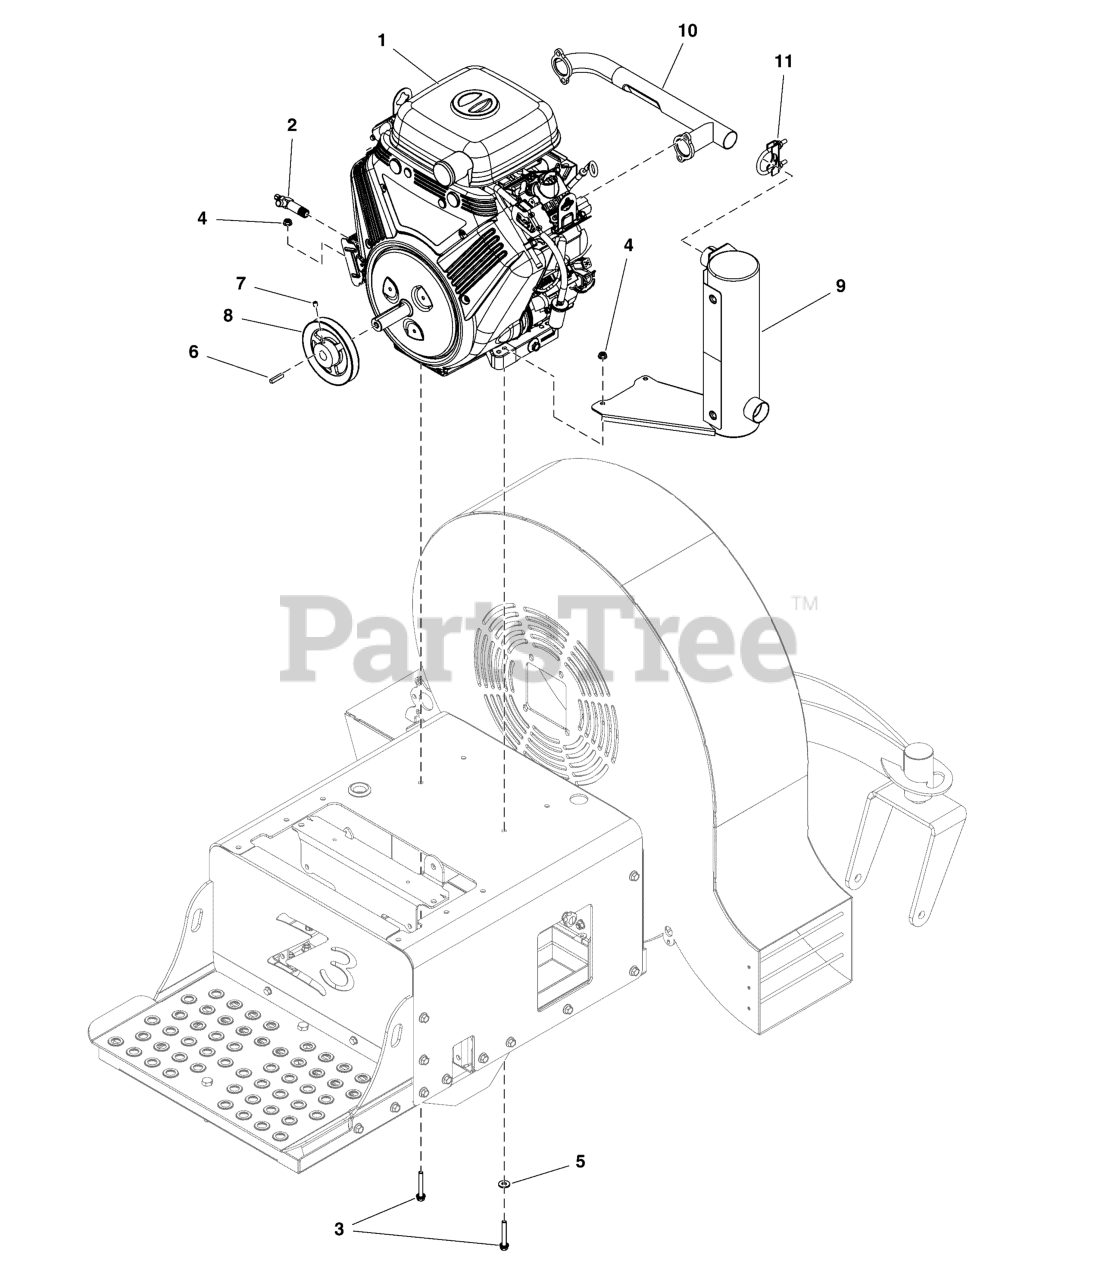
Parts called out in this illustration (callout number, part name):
2	VALVE, OIL DRAIN SHUT OFF
4	NUT, 5/16-18 HEX SERR
5	WASHER, 5/16 FLAT, CZ
6	KEY, 1/4 SQ X 1-1/4
7	SET SCREW, 5/16-18, BLK
10	MANIFOLD
11	CLAMP, Muffler
